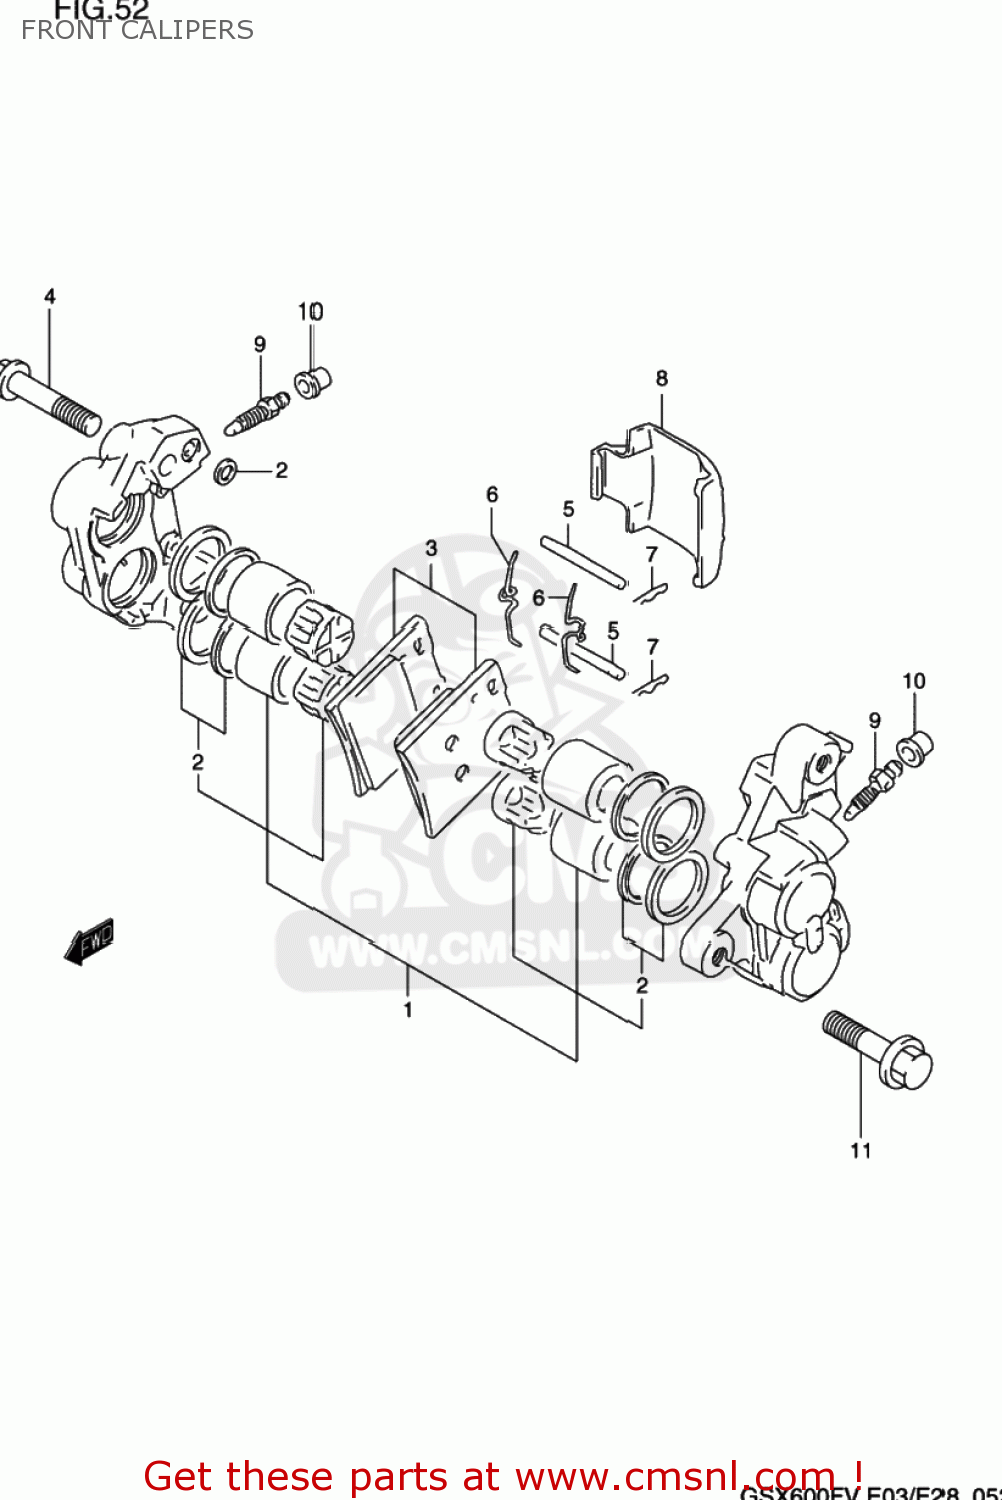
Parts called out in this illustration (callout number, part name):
1	PISTON SET
2	SEAL SET,PISTON
3	PAD SET (NAS)
4	BOLT,HOUSING
5	PIN,PAD
6	SPRING
7	CLIP,PAD PIN
8	COVER,CALIPER
9	BLEEDER
10	CAP,BLEEDER PLUG
11	BOLT
